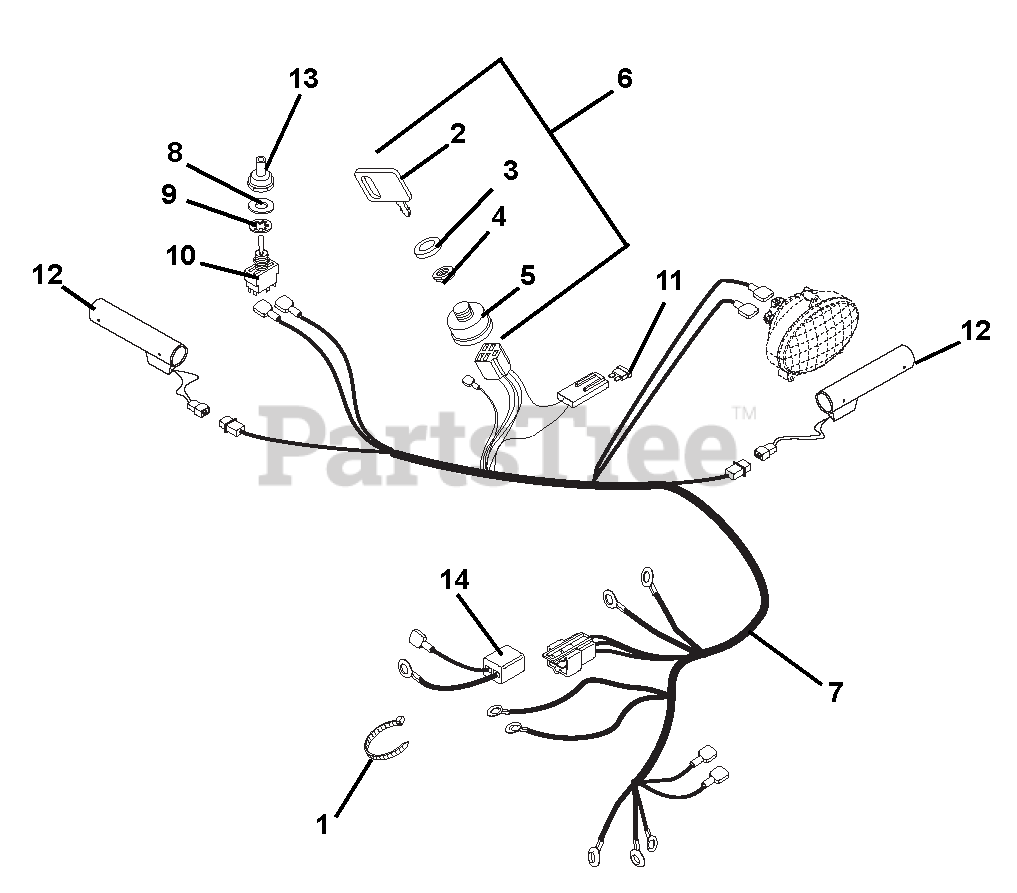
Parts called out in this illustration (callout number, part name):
1	CABLE TIE LG 5-1/2
2	KEY -W/CAP
3	CAP - IGNITION SWITCH
4	NUT-PANEL .625-32 GRECO
5	IGNITION SWITCH ASSEMBLY
6	SWITCH ASSEMBLY
7	HARNESS, WIRE-LIGHT HANDWARMER
7	HARNESS, WIRE-LT, HW, 12V
8	WSHR-FL-STL .505X.875X.024 PL
9	WSHR-LK-INT .563X.040 YWZC
10	SWITCH, ON/OFF
11	FUSE, 15 AMP.
12	HEATED GRIP, MAGURA
13	BOOT, SWITCH
14	HARNESS ADAPTER, BRIGGS 9A DC
14	HARNESS ADAPTER, BRIGGS 12V
